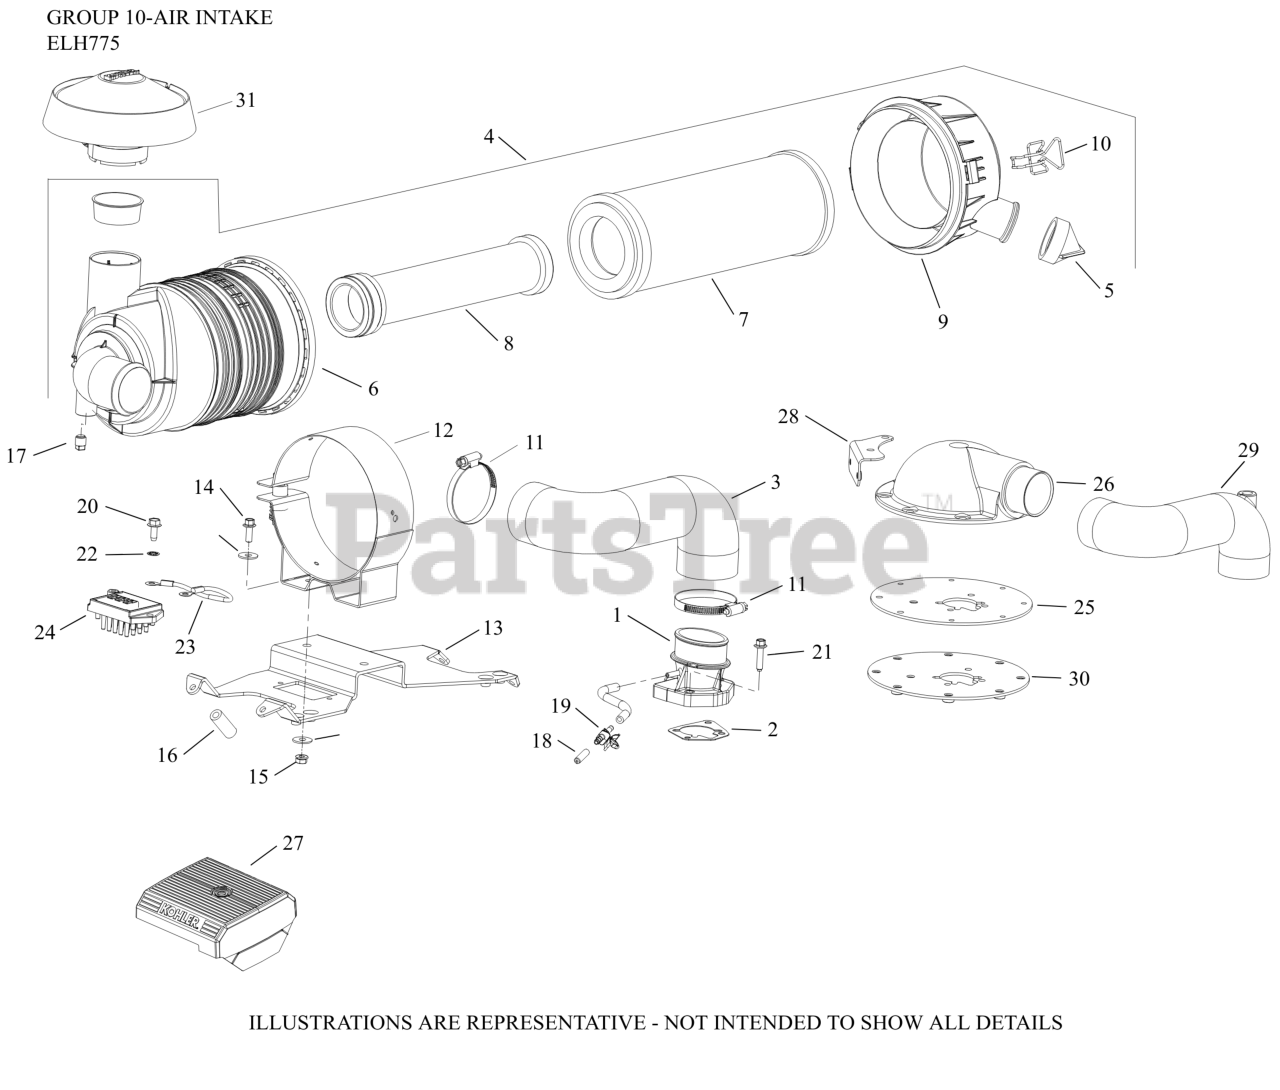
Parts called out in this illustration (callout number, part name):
1	KIT, REMOTE AIR CLEANER ADAPTER
2	GASKET, AIR CLEANER BASE
3	HOSE, AIR CLEANER
4	AIR CLEANER ASSY-USE 25 048 17-S
5	VALVE, DUST EJECTOR
6	HOUSING, HD AIR CLEANER
7	ELEMENT, AIR FILTER - PRIMARY
8	ELEMENT, AIR FILTER - SAFETY
9	COVER ASSEMBLY, AIR CLEANER
10	CLIP - USE 62 154 07-S
11	CLAMP, HOSE
12	AIR CLEANER BRACKET
13	AIR CLEANER BRACKET
14	SCREW, FLG M6X1.0X16
15	NUT, LOCK M6X1.0
17	PLUG, PIPE
18	CAP, MASKING
19	CONNECTOR, EVAPORATIVE
20	SCREW, THREAD FORMING
21	SCREW, FLG M6X1.0X25
22	WASHER, INT TOOTH LOCK 1/4"
23	KIT, GROUND, LEAD
24	REGULATOR, RECTIFIER
31	HOOD, INLET
